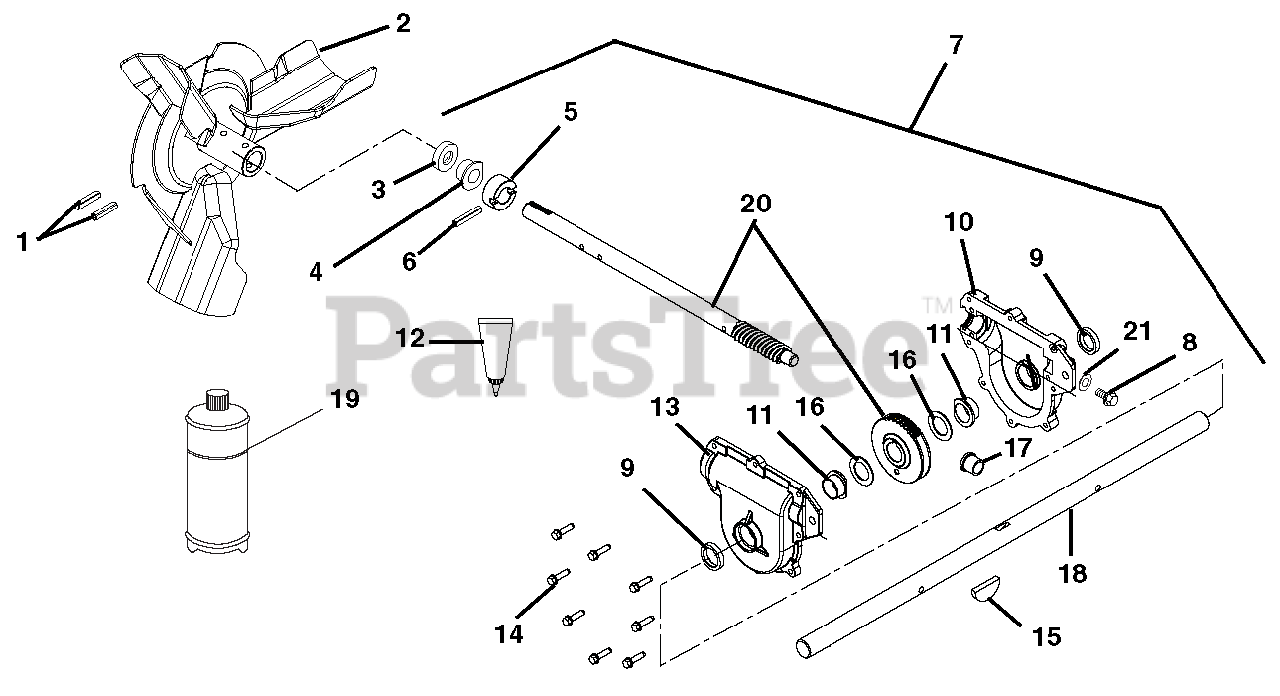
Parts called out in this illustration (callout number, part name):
1	PIN-ROLL .250X1.75
2	IMPELLER, 3 BLADE-14"
3	SEAL-OIL .875X1.375X.25 RBR OD
4	BSHG-FLG .876 X 1.500 X .750
5	THRUST COLLAR, .875" ID
6	PIN-GRV .250X1.50 TP E
7	GEAR CASE, ALUM-LARGE 32"
7	GEARCASE ASS'Y - 26" ALUMINUM
7	GEAR CASE, ALUM-LARGE 28"
8	SCR-TAP .38-16X.75 ROLOK YZ WX
9	SEAL-OIL 1.000X1.375X.250
10	GEARCASE, ALUMINUM, LH
11	BSHG-FLG 1.003X1.5X.625
12	LOCTITE 518 GASKET--6ML TUBE
13	GEARCASE, ALUMINUM, RH
14	@SCR-TAP .25-20X1.00 HWH TR YZ
15	KEY-WDRF .25X.875X.375 SAE A
16	WSHR-HRD-THRS 1.007X1.542X.062
17	BSHG-FLG .629 X 1.000 X .750
18	SHAFT, RAKE-32"
18	SHAFT, RAKE-26"
18	SHAFT, RAKE-28"
19	ARIENS 16 OZ.BOTTLE OF L2 LUBE
20	ASSY, WORM SHAFT & GEAR
21	WSHR-FIBER .437X.656X.032
